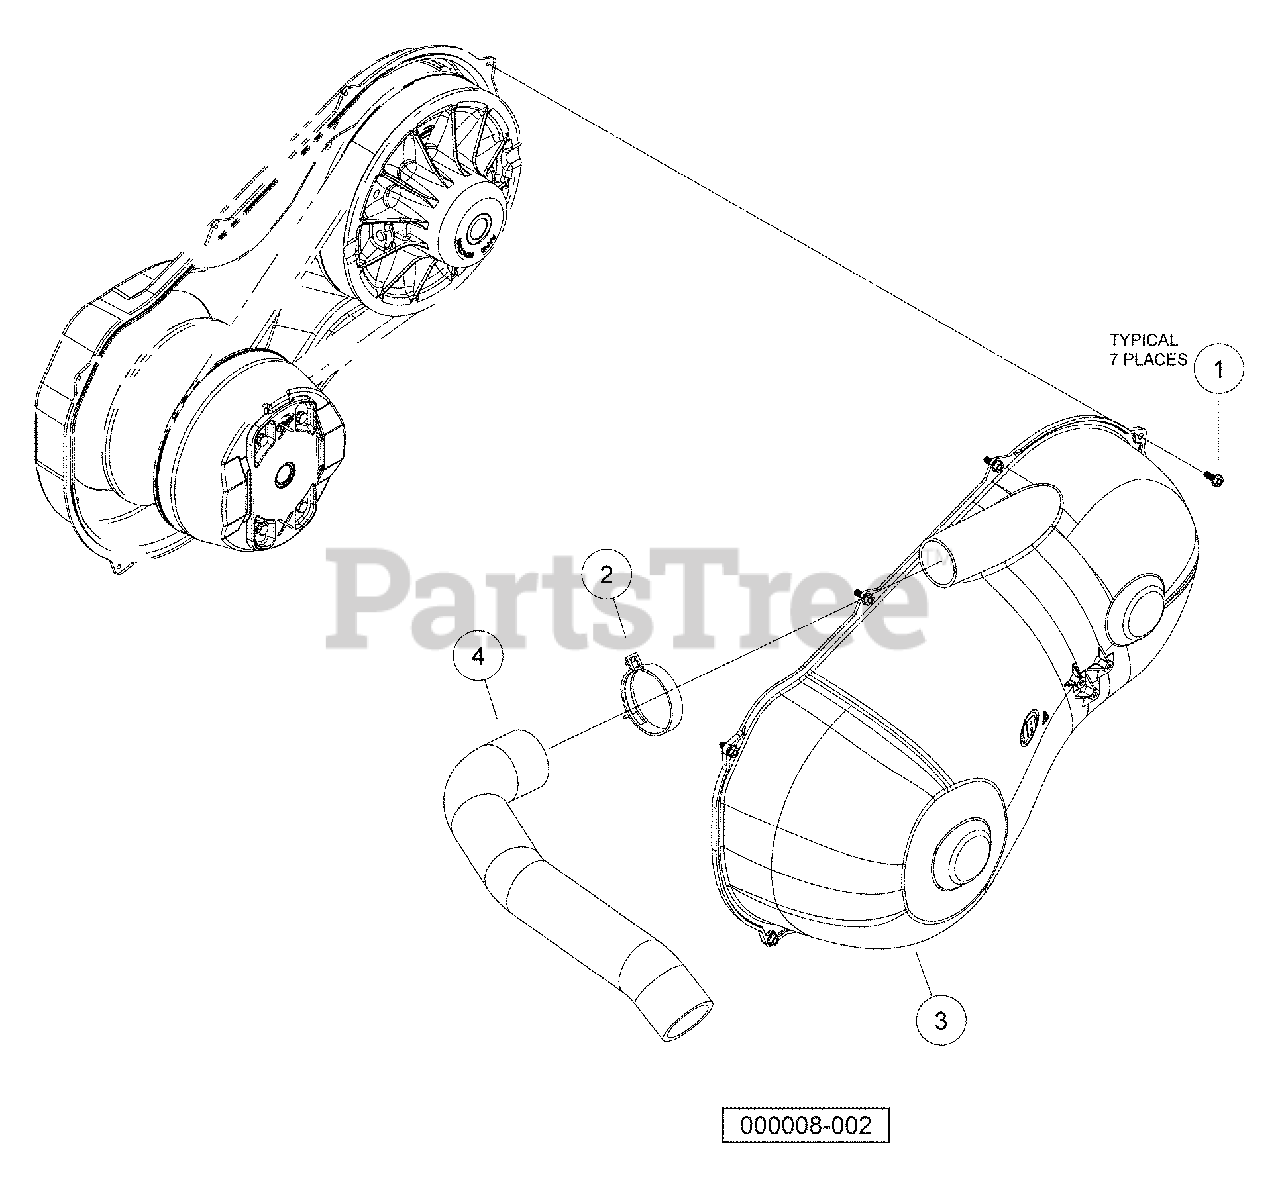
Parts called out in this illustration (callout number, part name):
1	Screw, M6 X 16 Tt Hx Fl Hd
2	Clamp, Hose, Ctb 64mm
3	Cover, CVT Outer
4	Hose, Outlet, Cvt
